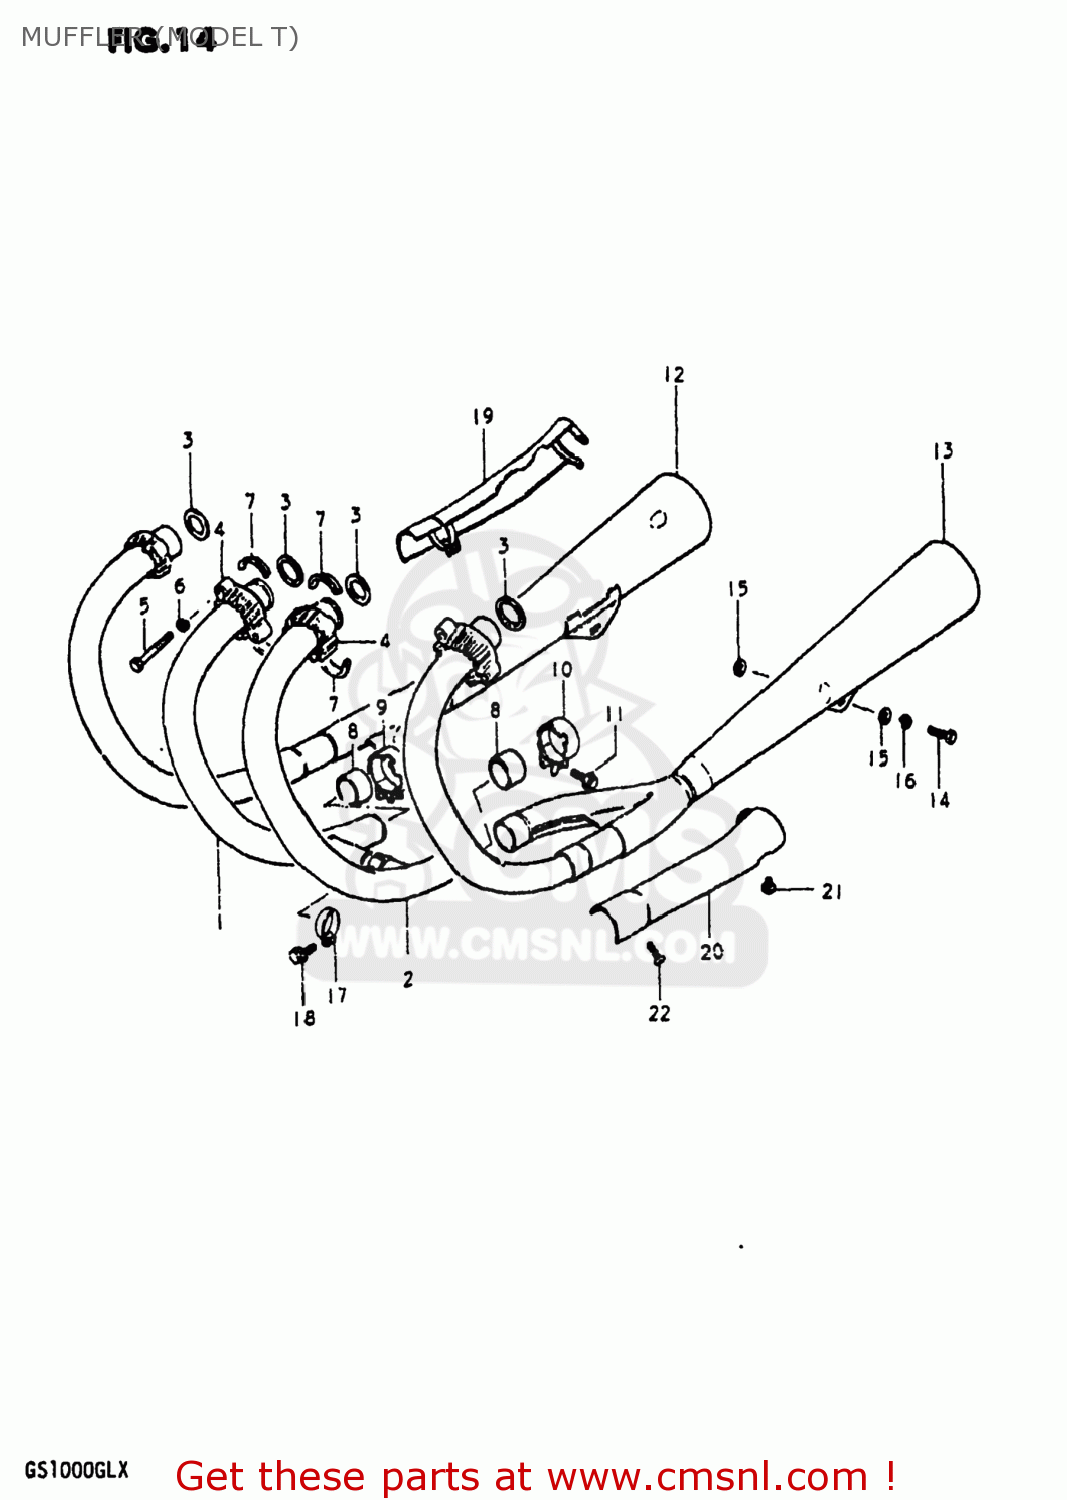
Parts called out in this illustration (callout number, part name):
1	PIPE,CENTER EXHAUST
2	COVER,EXHAUST PIPE
3	GASKET,EXHAUST PIPE (NAS)
4	CLAMP,EXHAUST PIPE
5	BOLT 8X45
6	LOCK WASHER
7	PLATE,EXHAUST
8	CONNECTOR,MUFFLER
9	CLAMP,MUFFLER CONNECTOR,R
10	CLAMP,MUFFLER CONNECTOR,L
11	BOLT
12	BODY,MUFFLER
13	BODY,MUFFLER
14	BOLT 10X30
15	WASHER
16	LOCK WASHER
17	CLAMP
18	BOLT
19	COVER,MUFFLER,R
20	COVER,MUFFLER
21	SCREW
22	SCREW
